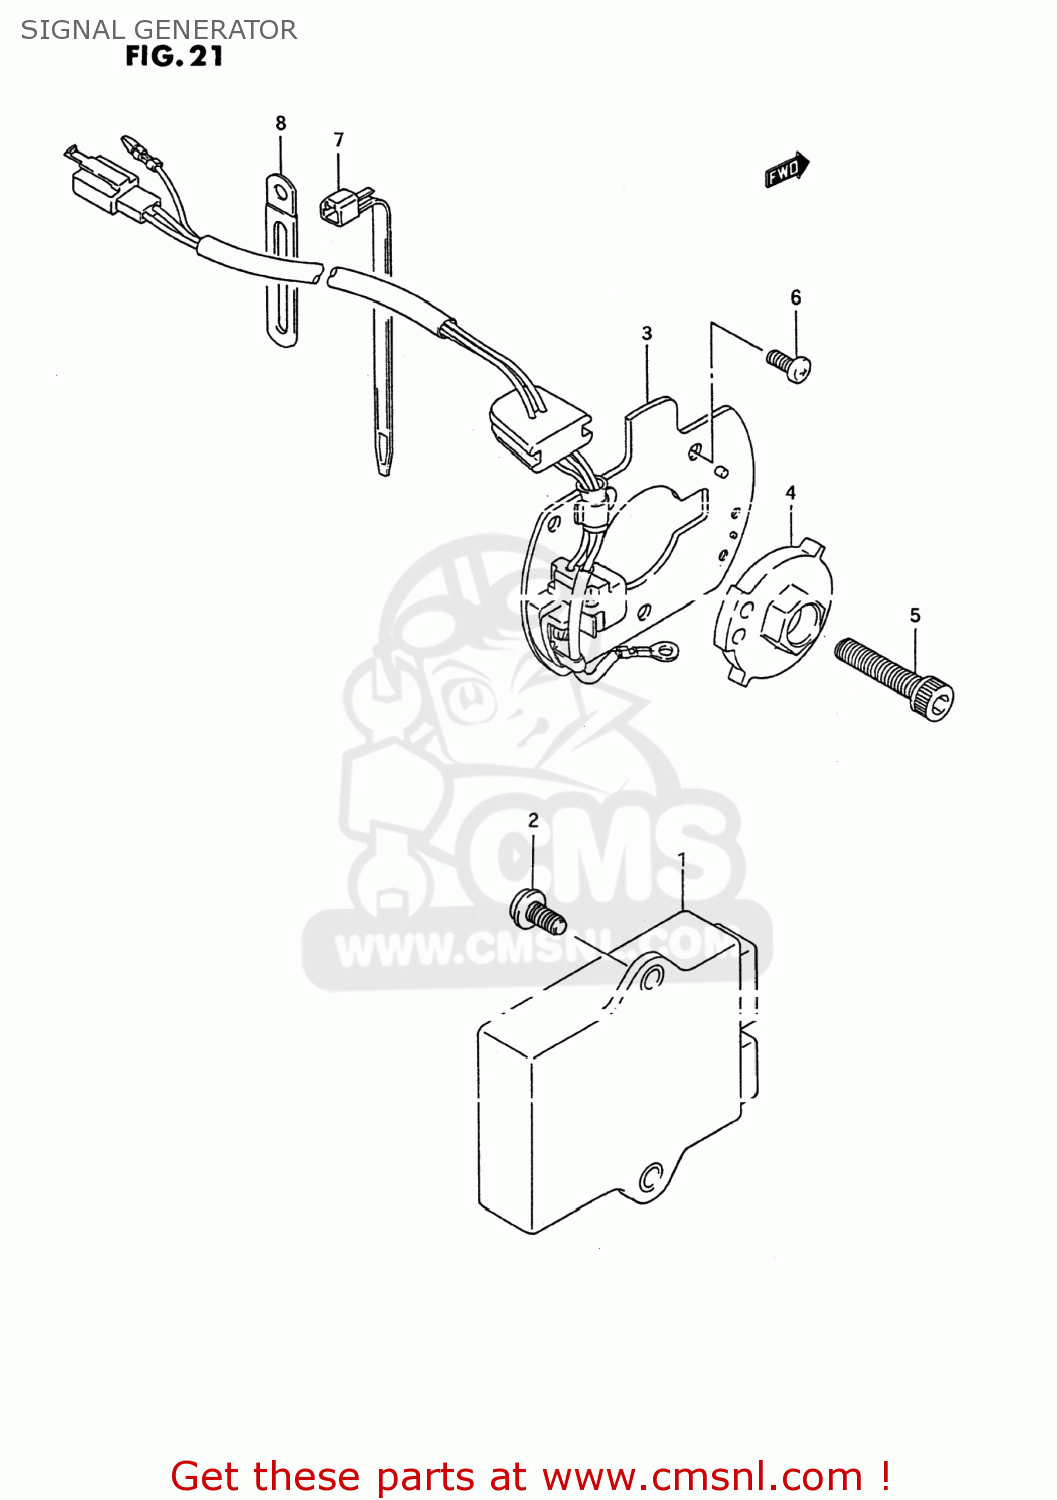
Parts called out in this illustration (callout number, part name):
1	IGNITOR ASSY
2	SCREW
3	GENERATOR ASSY,SIGNAL
4	ROTOR,SIGNAL
5	BOLT
6	SCREW
7	CLAMP(L:125)
8	CLAMP
